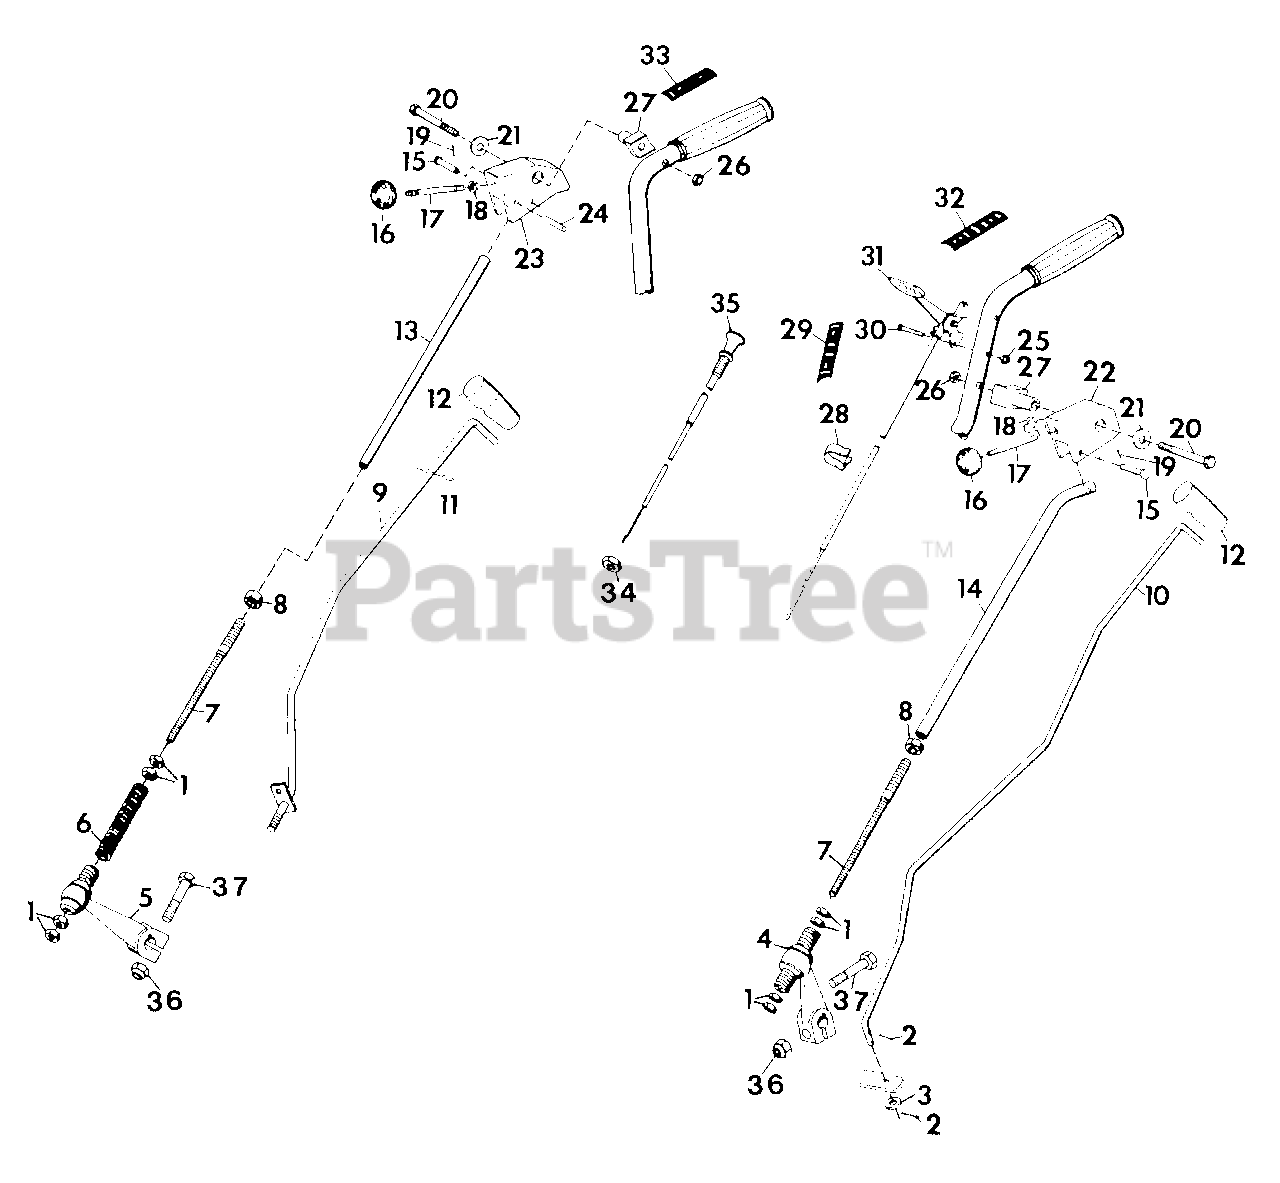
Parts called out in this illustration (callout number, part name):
1	JAM; 3/8-16 HEX
2	PIN, COTTER; .094 X 1.000
3	WASHER, FLAT; .406 X .812 X .065
4	ASSEMBLY, HI-LO LEVER
5	ASSEMBLY, FWD-REV LEVER
6	SPRING, FWD-REV NEUTRAL RETURN
7	ROD, CONTROL EXTENSION
8	NUT, JAM; 1/2-13
9	ROD, 2-SPEED CONTROL
10	ROD, ATTACHMENT
11	PIN, SPRING; .094 X .688
12	HANDLE; RUBBER SHIFTER
13	ROD, FWD-REV CONTROL
14	ROD, HI-LO CONTROL
15	PIN, CLEVIS; .375 X 1.250
16	KNOB, CONTROL
17	ROD, SHIFTER
18	NUT, JAM; 7/16-20 HEX
19	PIN, COTTER; .125 X .750
20	BOLT, HEX; 1/2-13 X 3-1/2
21	WASHER, FLAT; .500 X 1.062 X .095
22	SUPPORT, HI-LO SHIFTER ROD
23	SUPPORT, FORWARD-REVERSE SHIFTER ROD
24	PIN, SPRING; 1/4 X 1-1/8
25	NUT, LOCK; 10-24 WASHER INSERT
26	NUT
27	PIVOT, HANDLE LEVER
28	CLIP, CONDUIT
29	DECAL, GEAR SHIFT
30	SCREW, MACH; 10-24 X 1-1/2 PAN HD
31	LEVER, THROTTLE CONTROL; 12 H.P.
32	DECAL, THROTTLE
33	DECAL, FWD-REV
34	NUT, JAM; 3/8-24 HEX
35	CONTROL, CHOKE
36	NUT, LOCK 5/16-18 HEX HD WASHER INSERT
37	BOLT, HEX 5/16-18 X 2.00
